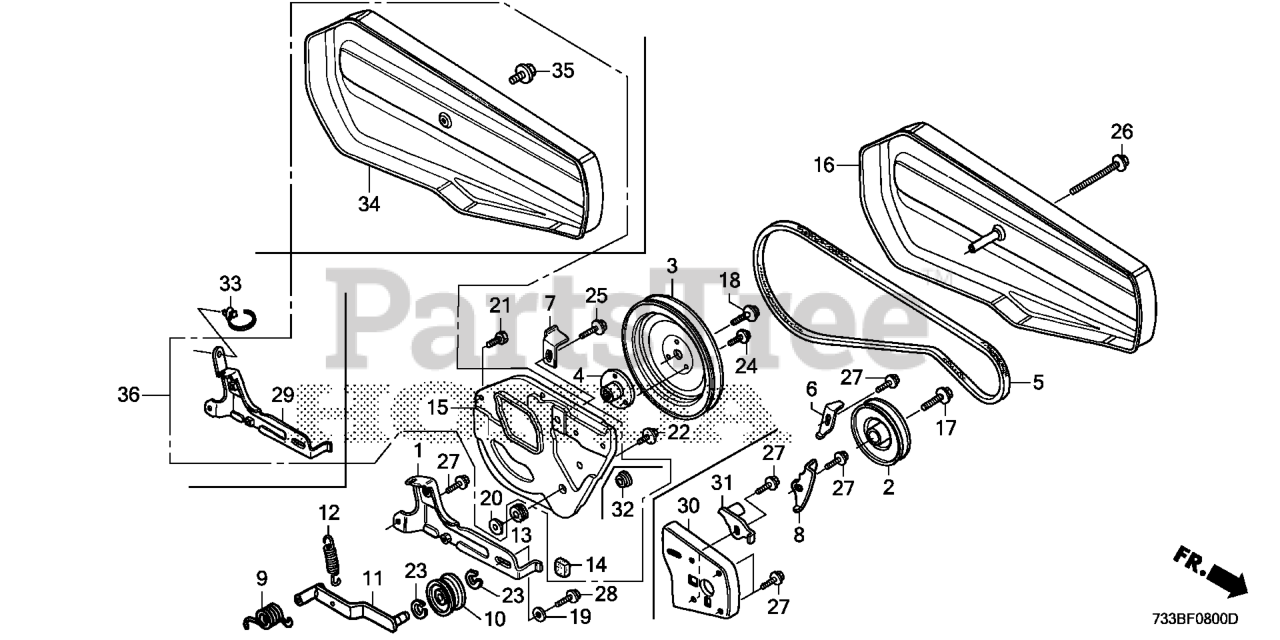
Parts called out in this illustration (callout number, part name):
2	PULLEY, DRIVE
3	PULLEY, DRIVEN
4	BOSS, DRIVEN PULLEY
5	V-BELT (SB-38)
6	STOPPER, BELT (UPPER)
7	STOPPER C, BELT
9	SPRING, TENSION ARM RETURN
10	ROLLER, TENSION
11	ARM, TENSION
12	SPRING, BELT TENSION
14	HOLDER, FUSE STAY
15	STAY, BELT COVER
17	BOLT, FLANGE (8X22)
18	BOLT, FLANGE (8X18)
19	WASHER (8MM)
20	WASHER, NUMBER BRACKET MOUNTING
21	BOLT, HEX. (6X8)
22	BOLT-WASHER (6X16)
23	CIRCLIP (OUTER) (10MM)
24	BOLT, FLANGE (6X10)
25	BOLT, FLANGE (6X12) Use up to Engine SN 1543277.
27	BOLT, FLANGE (8X16) Use from Engine SN 1000016.
28	BOLT, FLANGE (8X20) Use up to Engine SN 1609606.
29	STAY, ENGINE
30	PLATE, ENGINE ADJUSTING
31	STOPPER, BELT (LOWER)
32	GROMMET, WIRE
33	CLIP, HARNESS BAND (145MM) (BLACK)
34	COVER, BELT *R280* (POWER RED)
35	BOLT, FLANGE (6X8)
